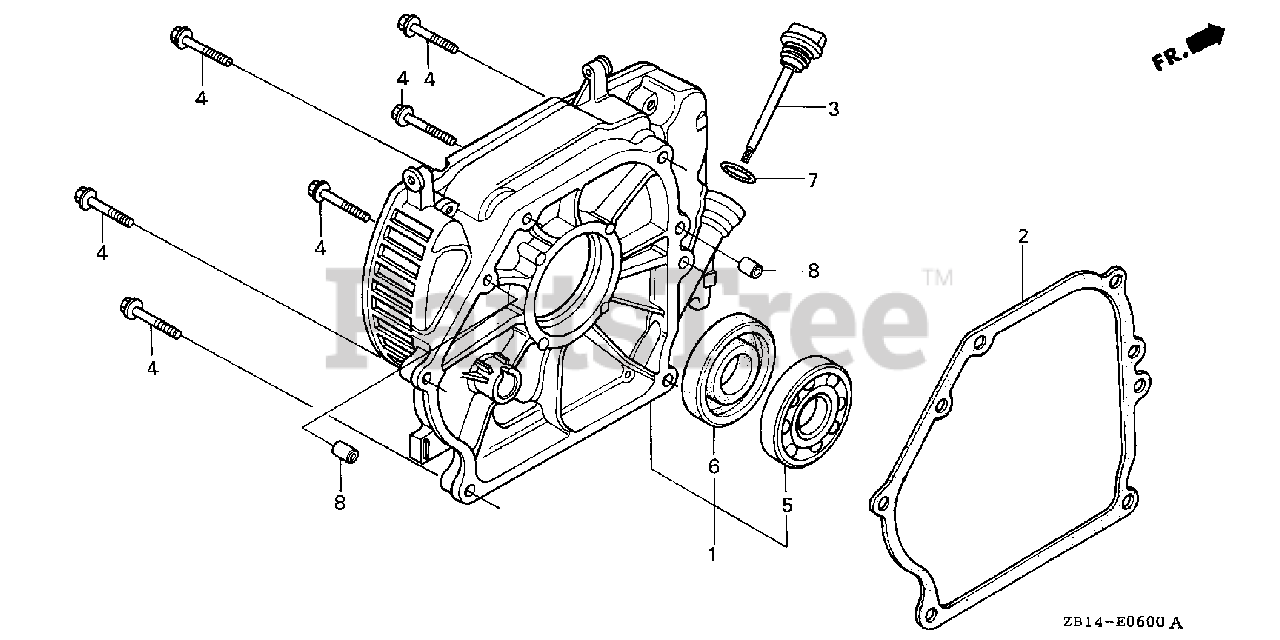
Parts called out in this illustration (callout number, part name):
1	COVER ASSY., CRANKCASE
2	GASKET, CASE COVER
3	CAP, OIL FILLER
4	BOLT, FLANGE (6X28) (CT200)
5	BEARING, RADIAL BALL (62/22)
6	OIL SEAL (22X41X6)
7	O-RING (16MM)
8	PIN, DOWEL (8X14)
